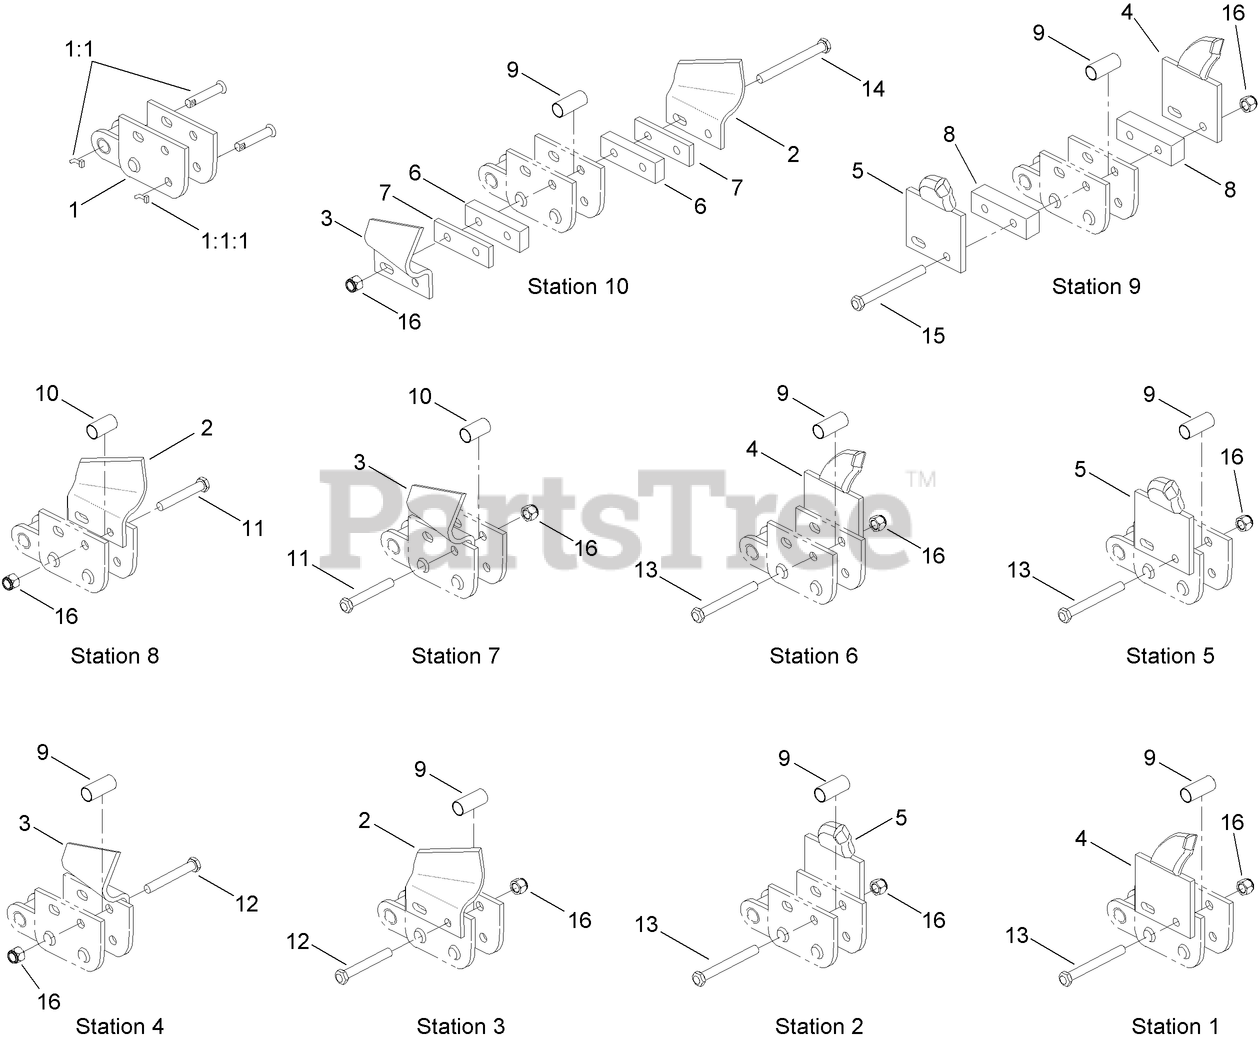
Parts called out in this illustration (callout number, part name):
1	CHAIN REPAIR LINK ASM
1:1	NOTCHED PIN AND KEEPER ASM
1:1:1	PIN-KEEPER
2	CUTTER-CUP, LH
3	CUTTER-CUP, RH
4	TOOTH-TERMINATOR, LH
5	TOOTH-TERMINATOR, RH
6	SPACER-FLAT (.500 Inch)
7	SPACER-FLAT (.250 INCH)
8	SPACER-FLAT (1.00 INCH)
9	SPACER-TUBE, OUTSIDE MOUNT
10	SPACER-TUBE, INSIDE CUP MOUNT
11	BOLT-HH
12	BOLT-HH
13	BOLT-HH
14	BOLT-HH
15	BOLT-HH
16	NUT-LOCK
